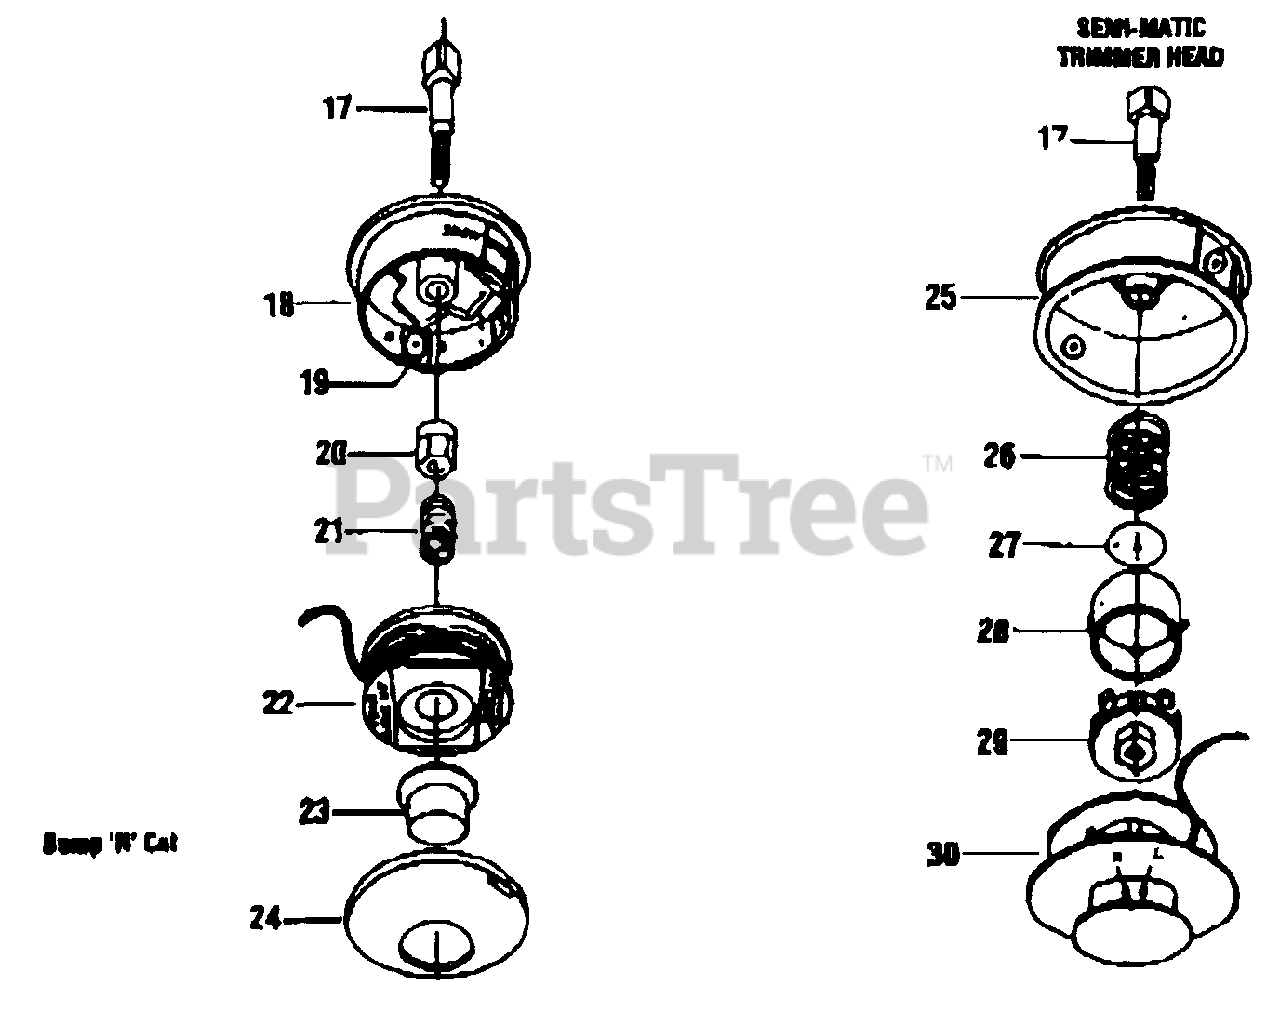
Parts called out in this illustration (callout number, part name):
17	BOLT, SHAFT - 8 -- LEFT HAND
22	SPOOL - LEFT
23	BUTTON
24	COVER
28	OUTER DRIVE
29	CAM, INNER LH
